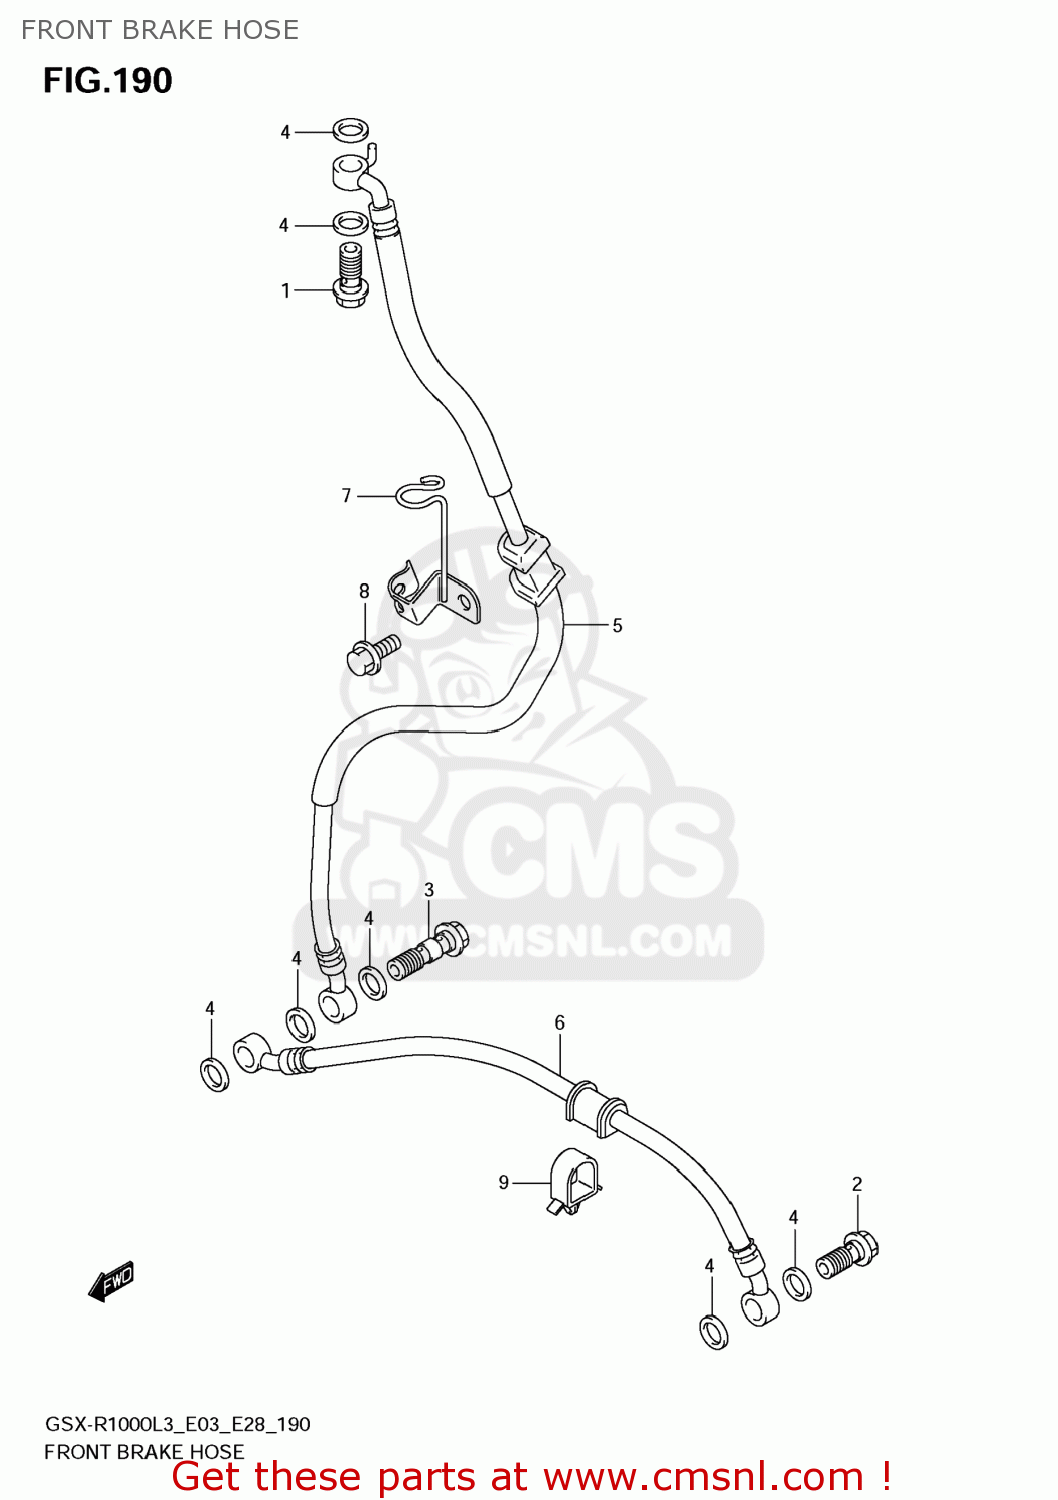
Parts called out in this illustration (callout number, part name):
1	BOLT UNION
2	BOLT UNION
3	BOLT UNION
4	WASHER(10X15X1.5)
5	HOSE,FR BRAKE NO.1
6	HOSE,FR BRAKE NO.2
7	CLAMP,FR BRAKE HOSE NO.1
8	BOLT
9	CLAMP
